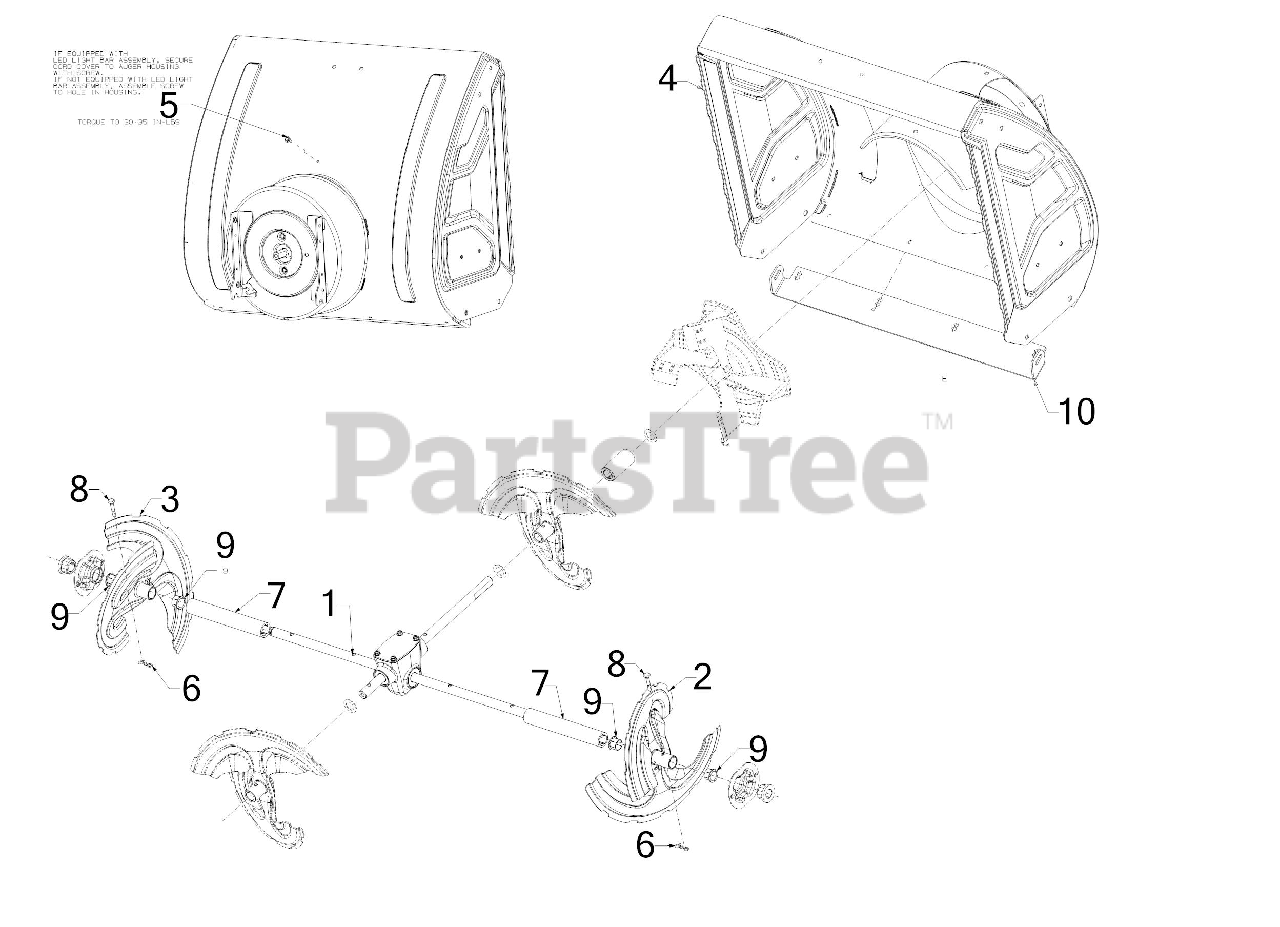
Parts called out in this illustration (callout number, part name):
1	28" AUGER GEARBOX ASSEMBLY
2	AUGER ASSEMBLY (LH)
3	AUGER ASSEMBLY (RH)
4	28" HD LED AUGER HOUSING ASSEMBLY
5	SCREW M6-1 x .625
6	BOW TIE COTTER PIN 1/4-5/16
7	SPACER
8	SHEAR PIN .25 x 1.50 GR2
9	FLANGE BUSHING
10	SHAVE PLATE 27.50
